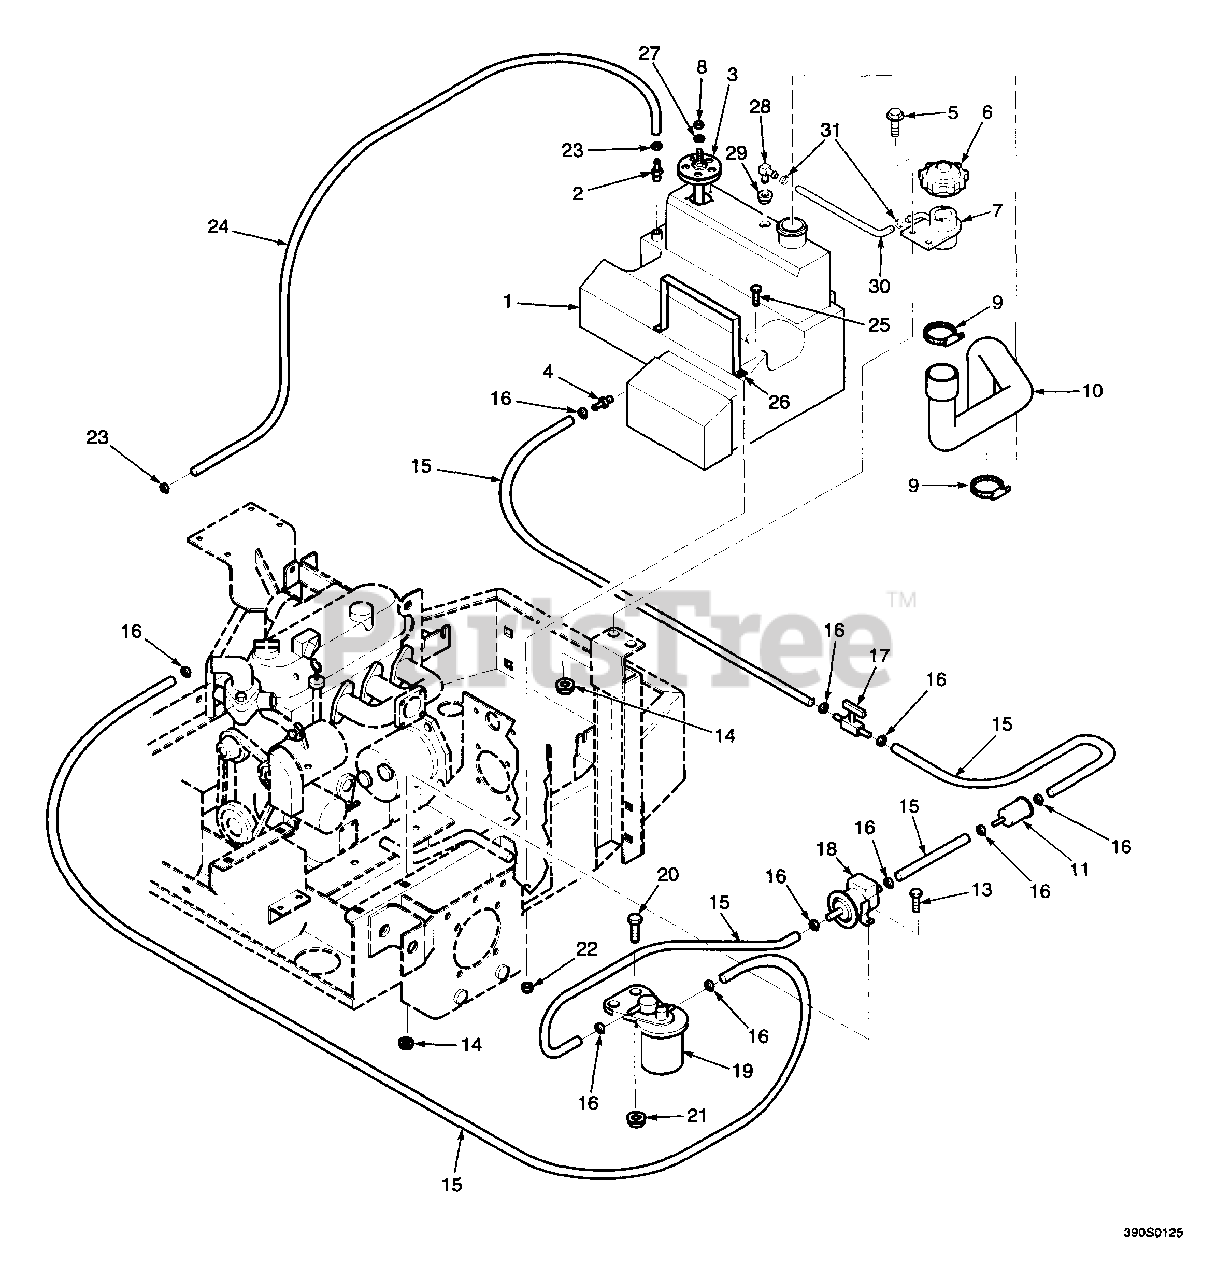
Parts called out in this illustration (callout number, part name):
1	Fuel Tank
2	Fitting, Return Line
3	Sender Unit, Fuel Level
4	Fitting, Hose
5	Serr. Fl. Hex Head Capscrew, 5/16-18 x 3/4
6	Cap, Diesel Fuel
7	Fill Neck Wlmt.
8	Hex Nut, #10-32
9	Clamp, Hose
10	Hose, Fuel Fill
11	Fuel Pre-Filter
13	Serr. Fl. Hex Head Capscrew, 1/4-20 x 3/4
14	Serr. Fl. Hex Nut, 1/4-20
15	Hose, Fuel Line
16	Clamp Hose
17	Valve, Fuel Shutoff
18	Fuel Pump, Electric
20	Serr. Fl. Hex Head Capscrew, 5/16-18 x 1
21	Serr. Fl. Hex Nut, 5/16-18
22	Hex Locknut, Elastic Stop, 1/4-20
23	Fuel Hose Clamp, 3/16
24	Hose Fuel Line, 3/16 x 33"
25	Serr. Fl. Hex Head Capscrew, 1/4-20 x 1-1/2
26	Strap, Fuel Tank
27	Lockwasher, #10
28	Elbow, 90 Deg.
29	Bushing, Fuel Tank
30	Hose, Fuel Vent, 1/2 x 21.5"
31	Clamp, Hose .75 OD Hose
